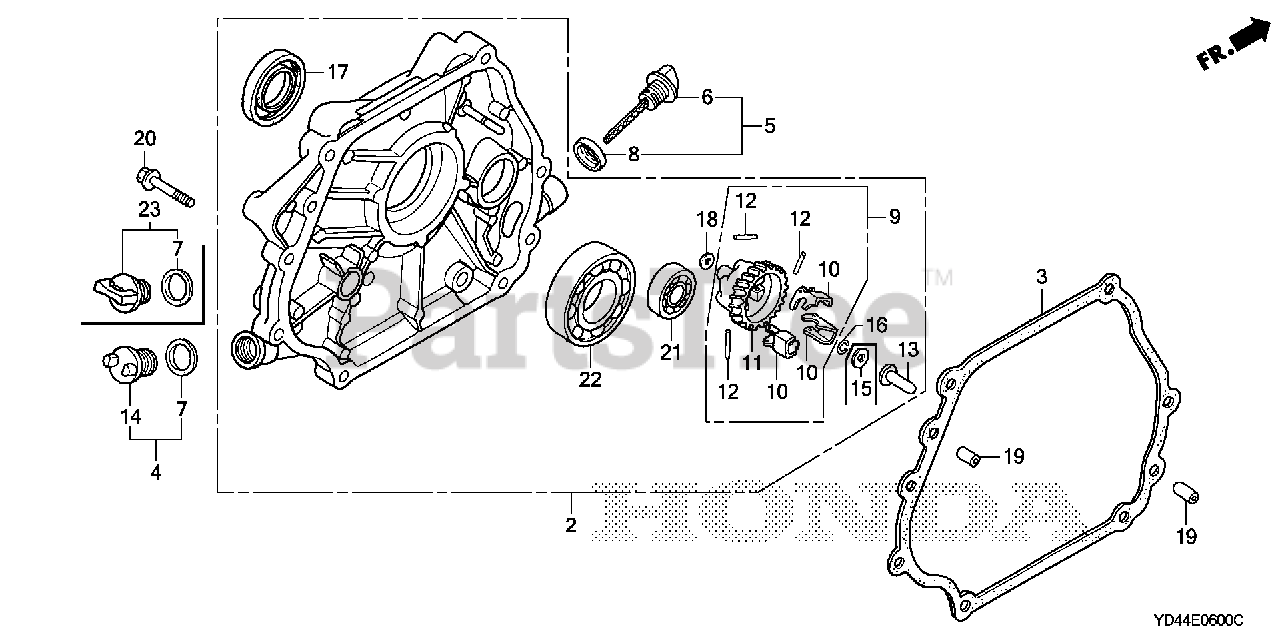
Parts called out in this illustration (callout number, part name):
2	COVER ASSY., CRANKCASE
3	GASKET, CASE COVER
4	CAP ASSY., OIL FILLER
5	CAP ASSY., OIL FILLER
6	CAP, OIL FILLER
7	GASKET, OIL FILLER CAP
8	GASKET, OIL FILLER CAP
9	GOVERNOR ASSY.
10	WEIGHT, GOVERNOR
11	HOLDER, GOVERNOR WEIGHT
12	PIN, GOVERNOR WEIGHT
13	SLIDER, GOVERNOR
14	CAP, OIL FILLER
16	CLIP, GOVERNOR HOLDER
17	OIL SEAL (35X52X8)
18	WASHER, PLAIN (6MM)
19	PIN, DOWEL (8X12)
20	BOLT, FLANGE (8X40) Use up to Engine SN 1003236.
21	BEARING, RADIAL BALL (6202)
22	BEARING, RADIAL BALL (6207)
